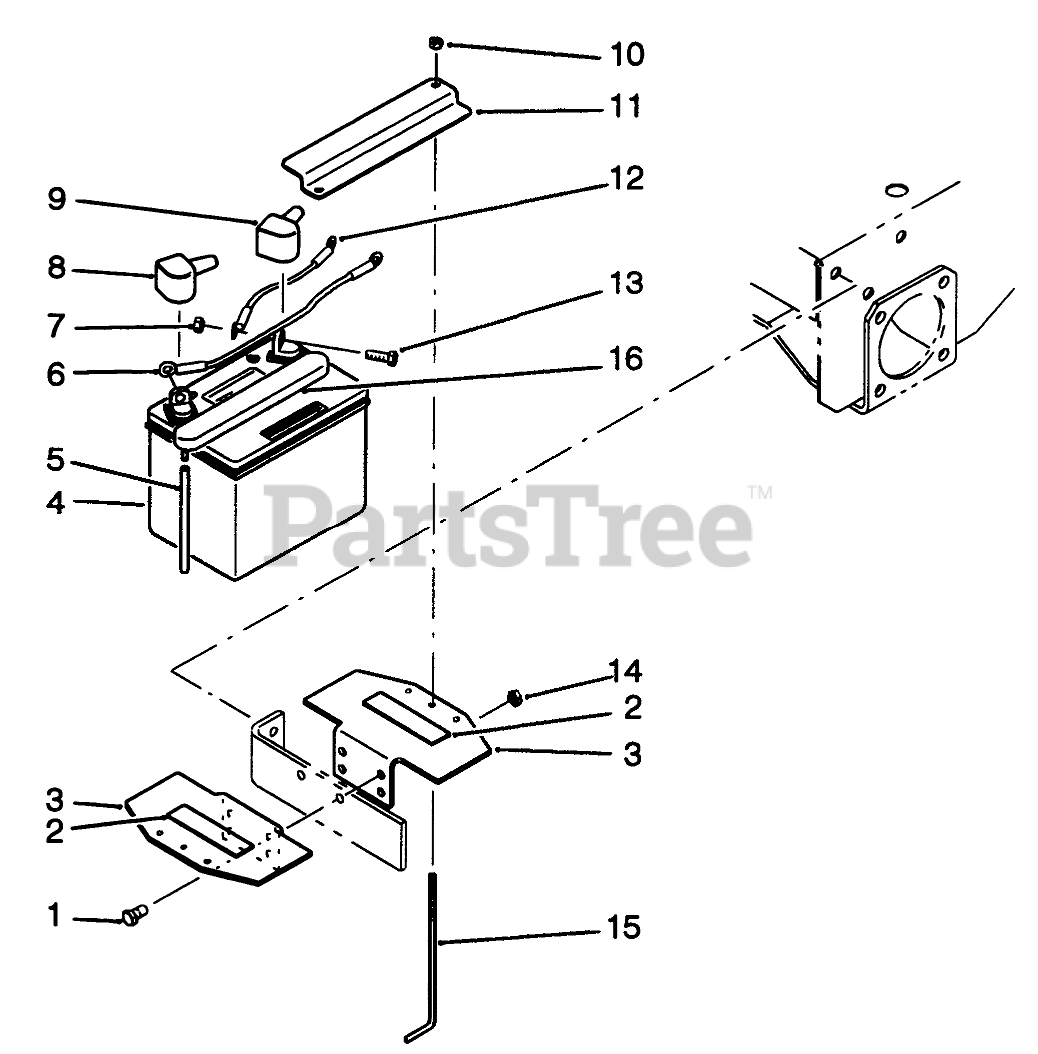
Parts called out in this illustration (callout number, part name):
1	SCREW-HH
2	PAD-TANK, FUEL
3	Holder-Battery
4	Battery
5	TUBE-VENT
6	WIRE ASM
7	NUT-KEPS
8	BOOT-TERMINAL, BLACK
9	BOOT-TERMINAL, RED
10	NUT-LOCK, NI
11	Clamp-Battery
12	WIRE ASM
13	SCREW-HH
14	NUT-LOCK, NI
15	ROD-SUPPORT, BATTERY
